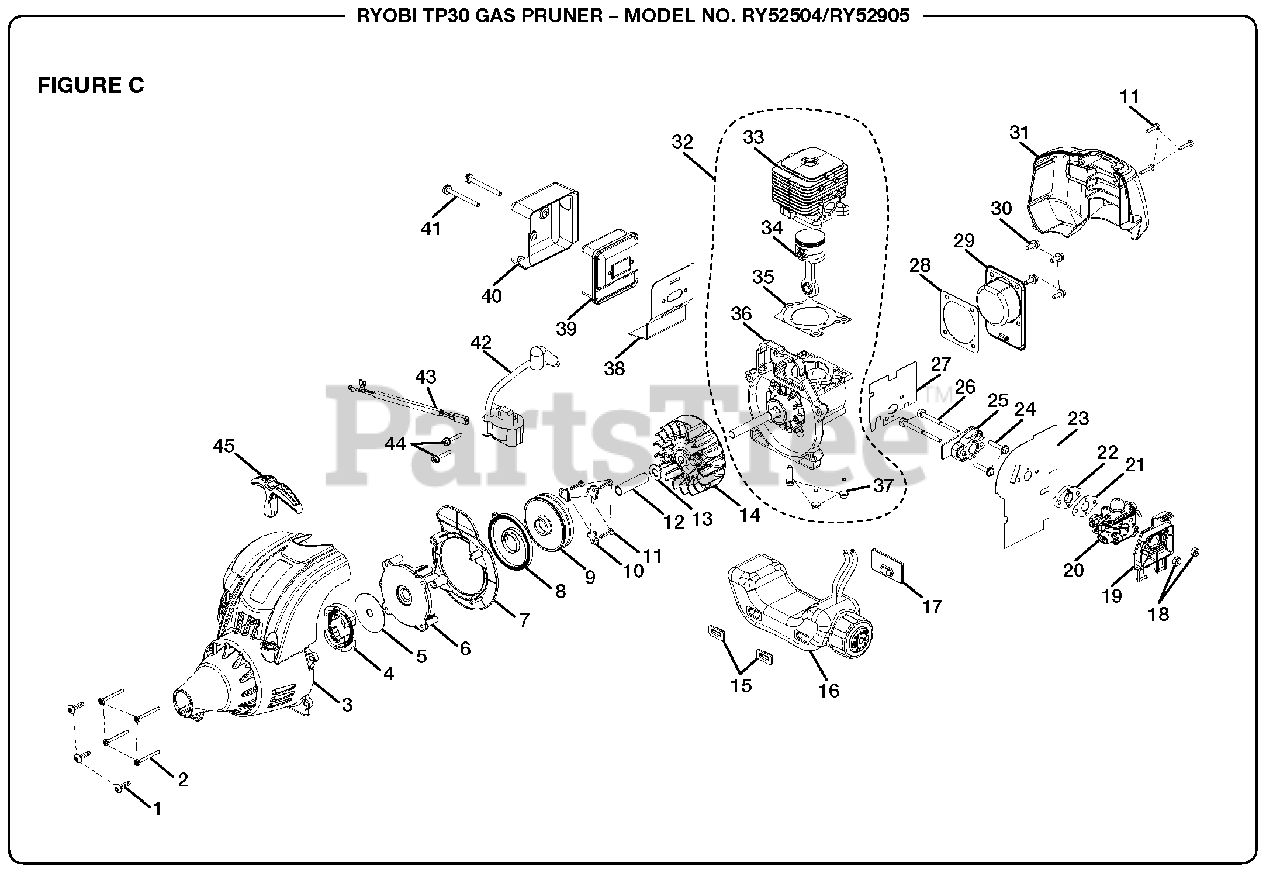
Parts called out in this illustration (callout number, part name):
1	Screw (10-24 x 3/4 in.)
2	Screw (M4 x 38 mm)
3	Starter Housing Assembly
4	Clutch Assembly
6	Starter Retaining
7	Baffle Plate
8	Spring & Container
9	Pulley Assembly
10	Pulley Retainer
11	Screw (M4 x 18 mm)
13	Washer
14	Rotor Assembly
15	Bumper
16	Fuel Tank & Cap Assembly
18	Lock Nut (10-24)
19	Air Filter Base
20	Carburetor Assembly
21	Carburetor Gasket
22	Spacer
23	Carburetor Gasket
24	Screw (10-24 x 1 in., Pan Hd.)
26	Screw (10 x 2-1/2 in.)
27	Heat Dam Gasket
28	Crankcase Gasket
29	Crankcase Cover
30	Pan Head Screw (10-24 x 14 mm)
31	Rear Housing
32	Short Block Assembly (Inc. Key Nos. 33-37)
33	Cylinder
34	Piston w/Rod Assembly
35	Cylinder Gasket
36	Crankcase Assembly
37	Screw (M5 x 0.8-20 mm)
38	Muffler Gasket
39	Muffler Assembly
40	Heat Shield
41	Screw (10-24 x 2-1/8 in.)
42	Ignition Module
43	Electrical Wire Assembly
44	Screw (M4 x 25 mm)
45	Starter Grip
